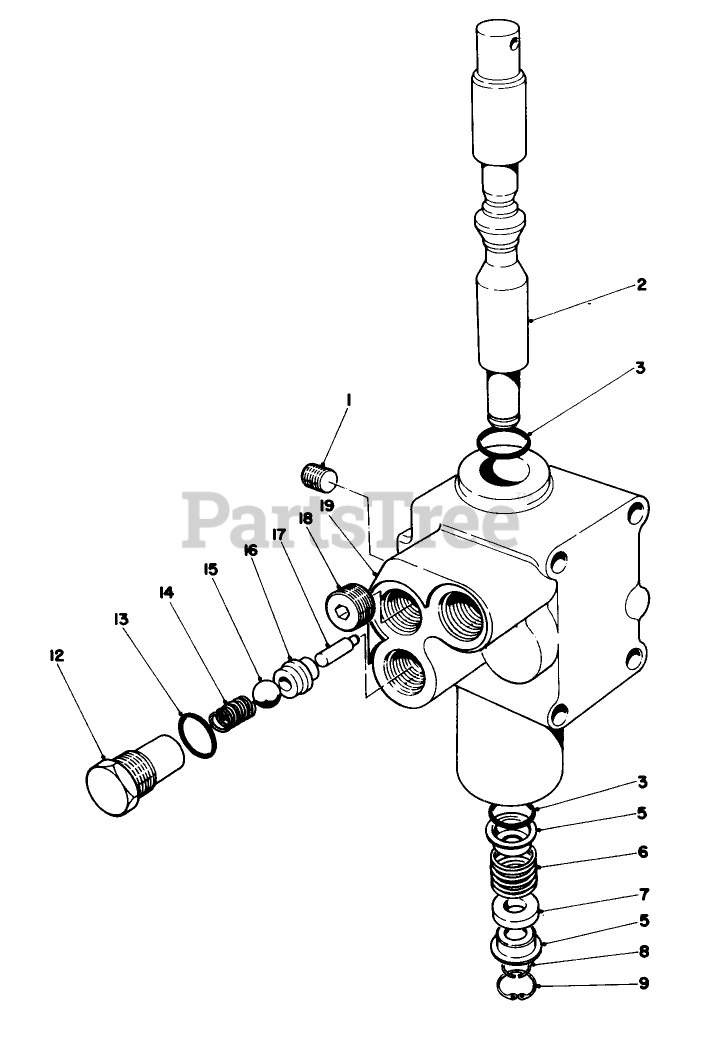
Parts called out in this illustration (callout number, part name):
2	SPOOL
3	O-RING
5	RETAINER
6	SPRING
7	FLOAT SPACER
8	RING-SNAP
9	RING-SNAP
13	O-RING
14	SPRING
16	SEAT-VALVE
